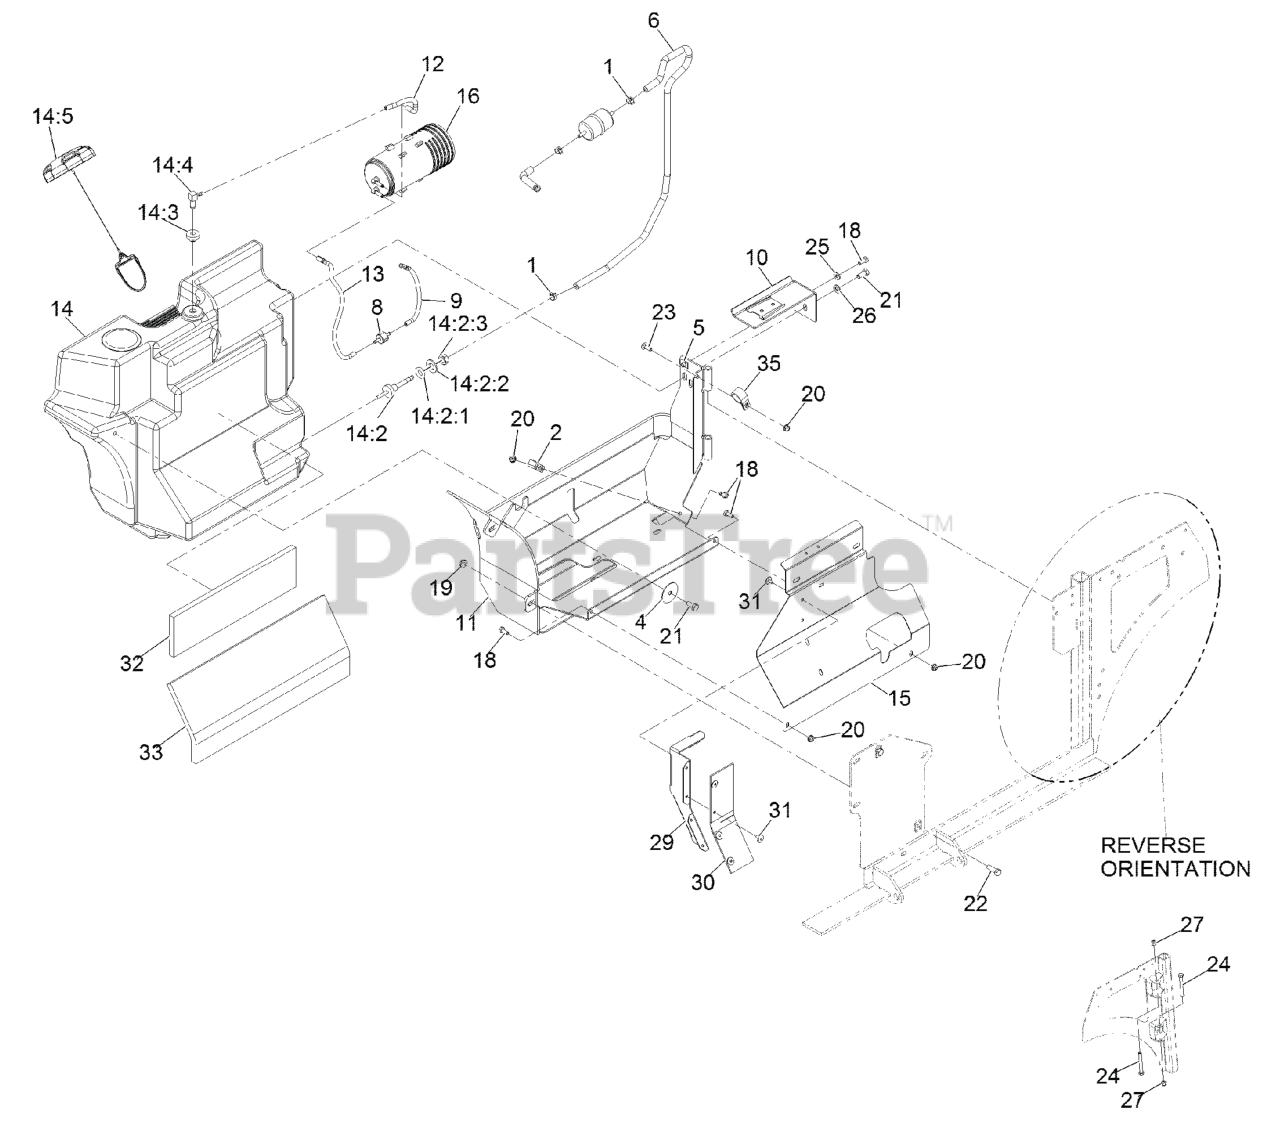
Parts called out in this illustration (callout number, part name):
1	CLAMP-HOSE
2	CLIP-LOOM
6	FUEL LINE ASM
8	VALVE-CHECK, VACUUM
9	HOSE-VENT, FORMED
10	CANISTER BRACKET ASM
11	TANK FRAME ASM
12	HOSE-VENT, FORMED
13	HOSE-VENT, FORMED
14	FUEL TANK ASM
14:2	FITTING-FUEL, BULKHEAD
14:2:1	O-RING,BULKHEAD FITTING
14:2:2	WASHER-FLAT
14:2:3	NUT-JAM
14:3	BUSHING
15	PANEL-TANK SHIELD
16	CANISTER-CARBON, 800CC
18	SCREW-HH
21	SCREW-HH
22	SCREW-HH
23	BOLT-CARR
24	SCREW-HH
25	WASHER-FLAT
26	WASHER-PLAIN
27	NUT-LOCK, NI
29	DEFLECTOR-AIR
30	FLAP-RUBBER
31	RIVET-POP
32	INSULATION-FOAM PAD, FRON
33	INSULATION-FOAM PAD, REAR
35	R-CLAMP
